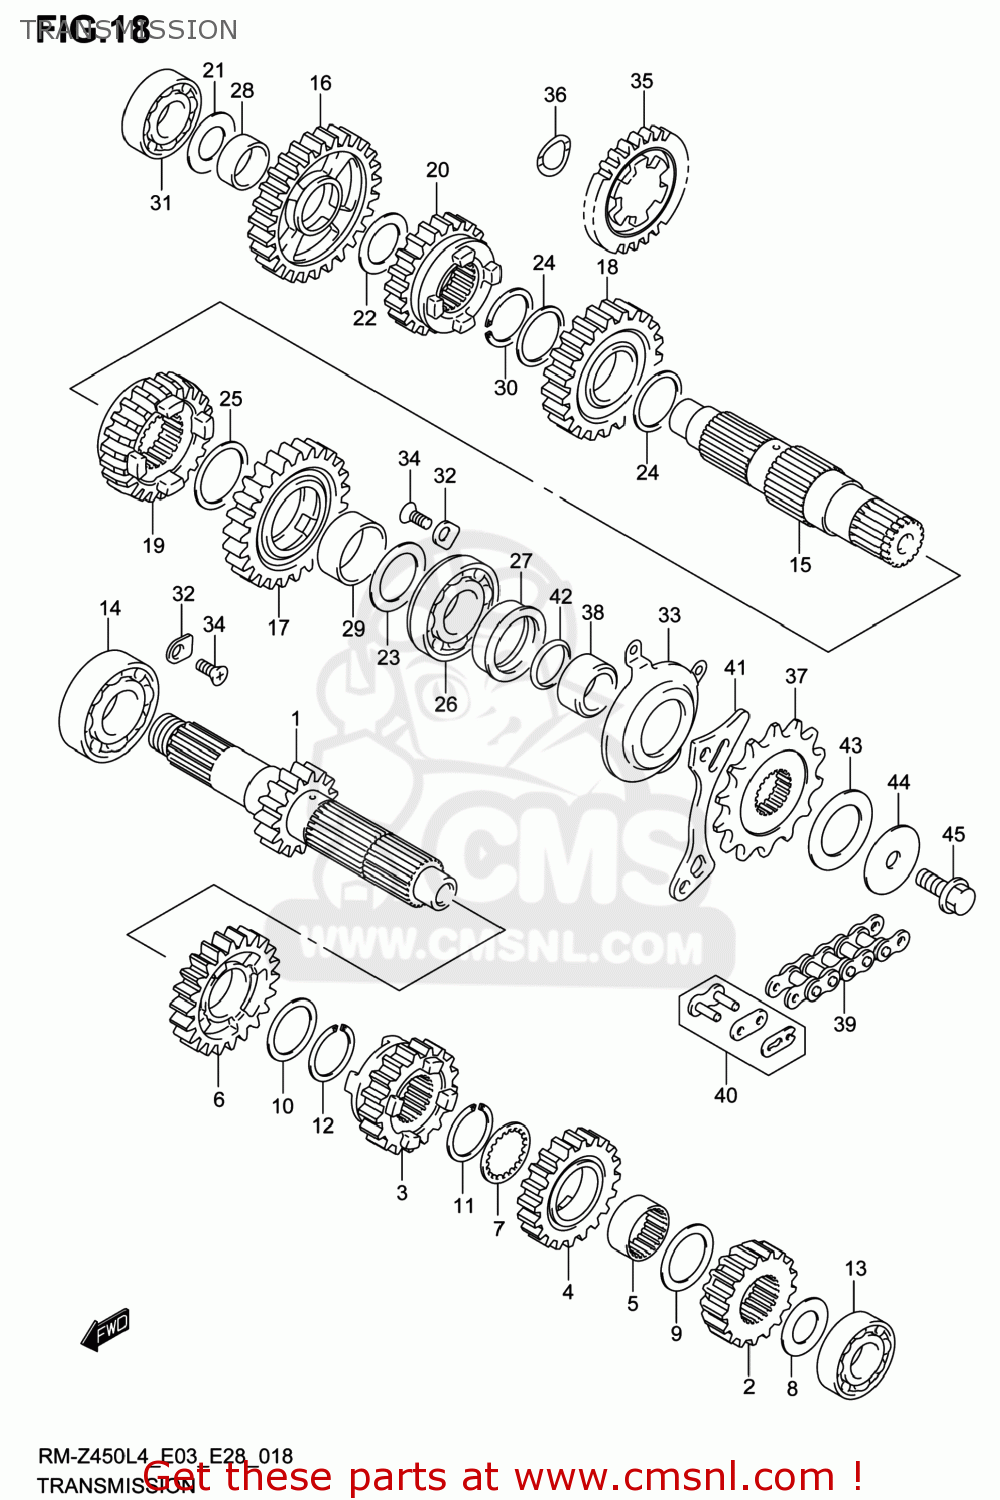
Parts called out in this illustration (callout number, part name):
1	SHAFT,COUNTER
2	GEAR,2ND DRIVE
3	GEAR,3RD DRIVE
4	GEAR,4TH DRIVE
5	BUSH,4TH DRIVE GEAR
6	GEAR,5TH DRIVE
7	WASHER,LOCK
8	SHIM(17X30X1)
9	SHIM(25X34X1)
10	SHIM(25X32X1)
11	CIRCLIP
12	CIRCLIP
13	BEARING
14	BEARING
15	SHAFT,DRIVE
16	GEAR,1ST DRIVEN
17	GEAR,2ND DRIVEN
18	GEAR,3RD DRIVEN
19	GEAR,4TH DRIVEN
20	GEAR,5TH DRIVEN
21	SHIM(17X30X1)
22	SHIM(20X30X1)
23	SHIM(24X34X1)
24	SHIM(25X30X1)
25	SHIM(27X33X1)
26	BEARING(24X56X14)
27	SEAL,OIL(31X40X6.7)
28	BUSH(20X24X10)
29	BUSH(27X31X13)
30	CIRCLIP
31	BEARING
32	RETAINER,COUNTER BEARING,R
33	RETAINER,DRIVE SHAFT OIL SEAL
34	SCREW(6X12)
35	GEAR,KICK STARTER IDLE
36	WASHER,KICK IDLE
37	SPROCKET,ENGINE(13T)
38	SPACER,ENGINE SPROCKET
39	CHAIN,DRIVE
40	JOINT SET,CHAIN
41	PLATE,FR CHAIN GUIDE
42	D RING,SPROCKET SPACER
43	WASHER,ENGINE SPROCKET WAVE
44	WASHER,ENGINE SPROCKET
45	BOLT(8X30)
